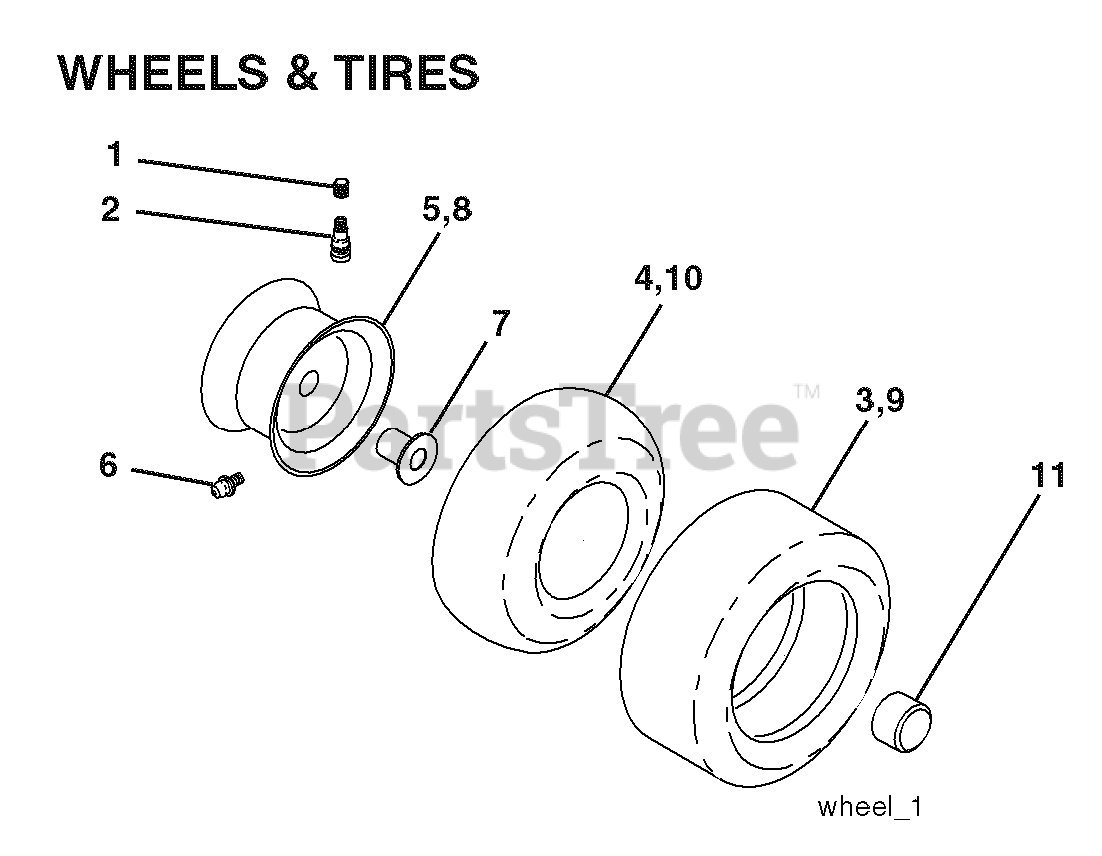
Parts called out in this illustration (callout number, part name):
2	VALVE STEM LT
3	TIRE HEAVY DUTY
4	TUBE.5.3/4.5/6
5	RIM ASM 6" FRONT SILVER
6	FITTING LT
7	BEARING T
8	RIM ASM 8" REAR SILVER
9	TIRE.TS.20X10-8
10	TUBE
11	CAP, AXLE BLK
